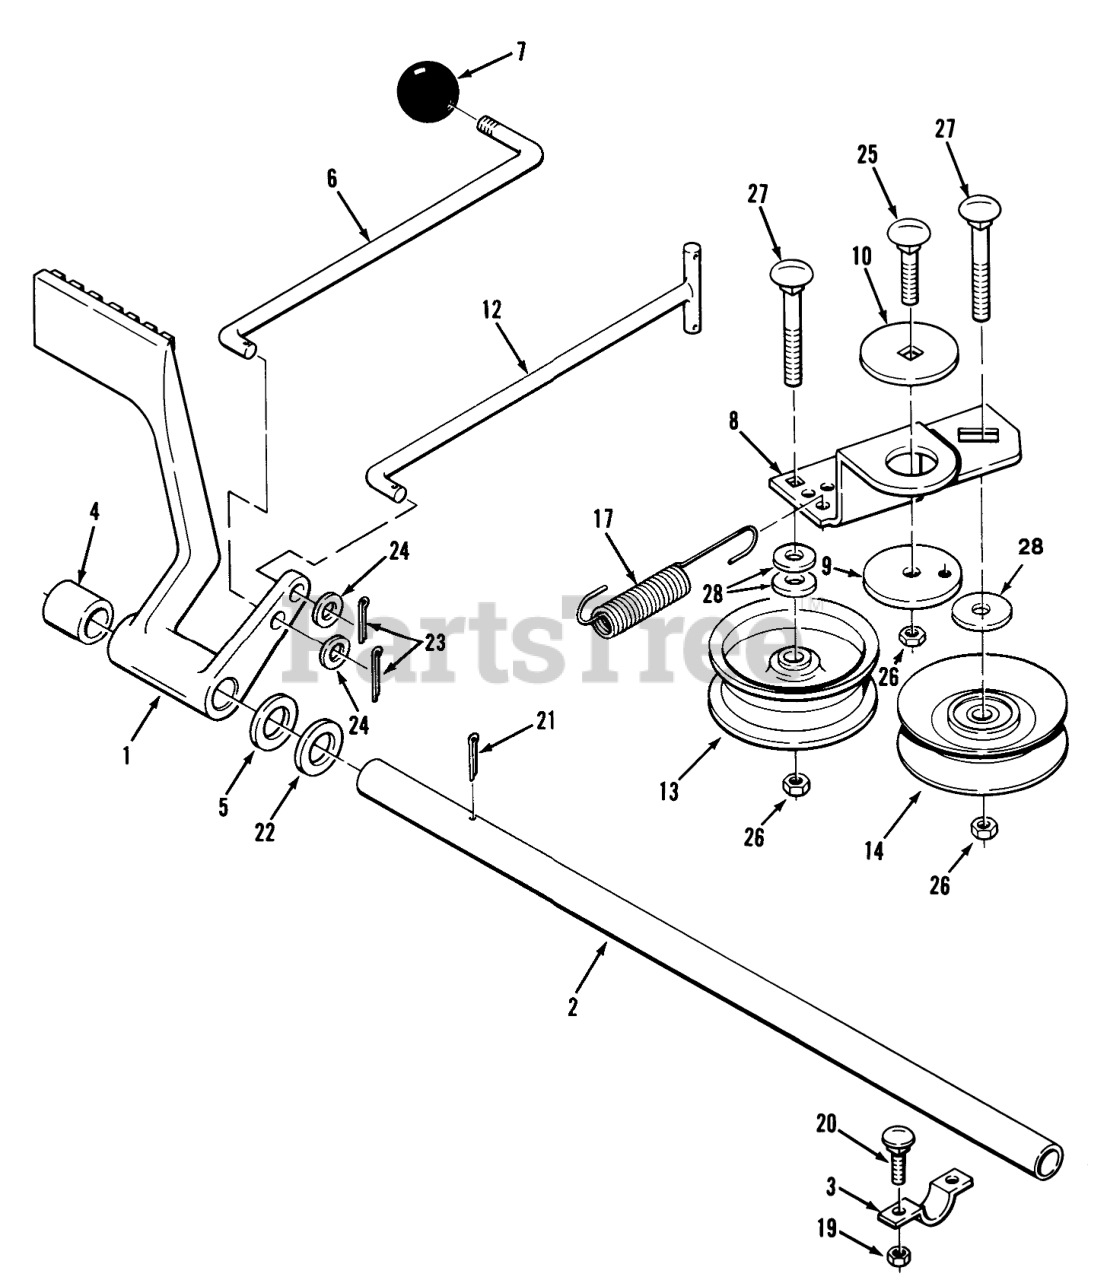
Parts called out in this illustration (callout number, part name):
1	PEDAL-BRAKE R
2	SHAFT PEDAL
3	CLAMP
4	SPACER
5	WASHER-WAVE
6	ROD-BRAKE LOCK B
7	KNOB
8	ARM-IDLER R
9	BUSHING
10	WASHER-BEARING
12	ASSY-ROD FRONT BR
13	PULLEY IDLER
14	PULLEY-IDLER
17	SPRING
19	NUT-LOCK, NI
20	BOLT-CARR
21	PIN-COTTER
22	Washer
23	PIN-COTTER
24	WASHER-PLAIN
25	BOLT-CARR
26	NUT-LOCK, NI
27	SCREW-CARR
28	WASHER-FLAT
29	WASHER-FLAT
